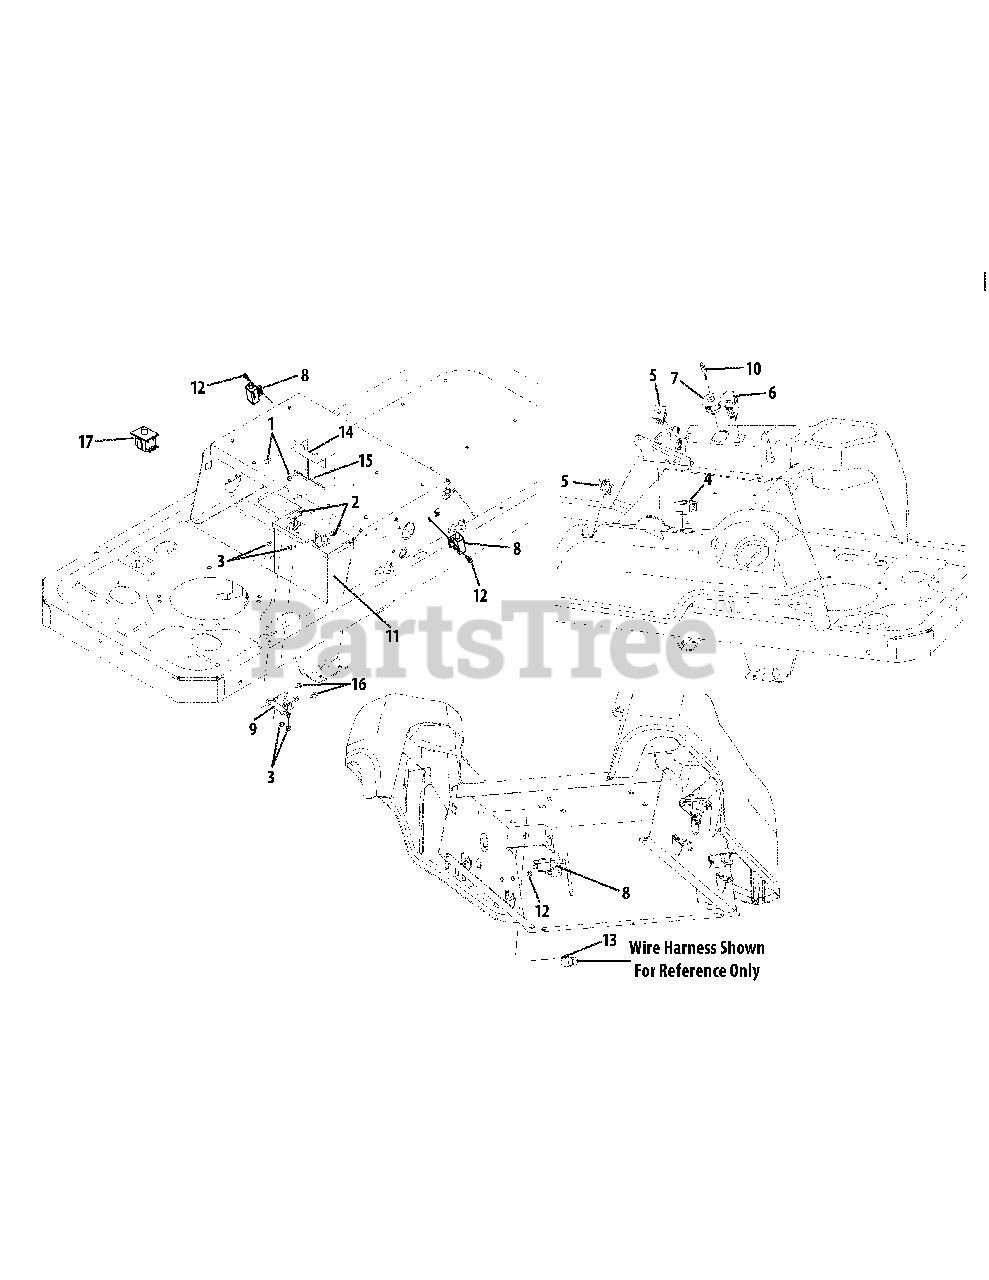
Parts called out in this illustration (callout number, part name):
1	Hex Screw, 1/4-20 x .5
2	Hex Screw, 1/4-20 x .75
3	Hex Nut, 1/4-20
4	Hour Meter
5	Double Pole — Neutral Switch
6	PTO Switch
7	Ignition Switch
8	Interlock Switch
9	Solenoid
11	Battery, 235 CCA
12	Shoulder Screw, #10-32 x .500
13	Cable Tie
14	Battery Hold-down
15	Trim Strip
16	Hex Screw, 1/4-20 x .375
17	Seat Switch
